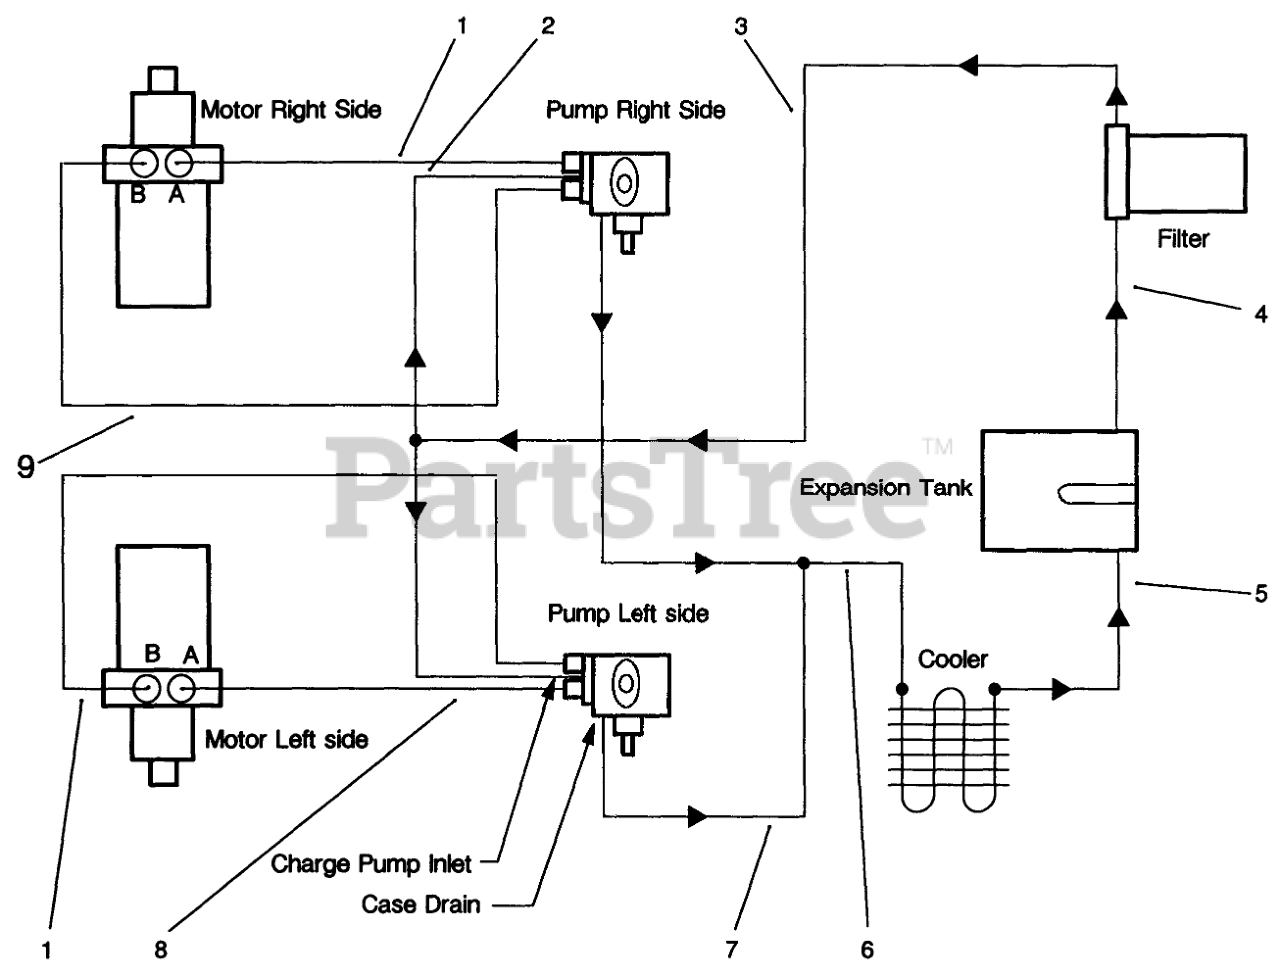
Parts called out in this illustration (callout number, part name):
1	HYDRAULIC HOSE ASM
2	HYD HOSE ASM
3	HYDRAULIC HOSE ASM
4	HYD HOSE ASM
5	HYDRAULIC HOSE ASM
6	HYDRAULIC HOSE ASM
7	HYD HOSE ASM
8	HYDRAULIC HOSE ASM
9	HYDRAULIC HOSE ASM
